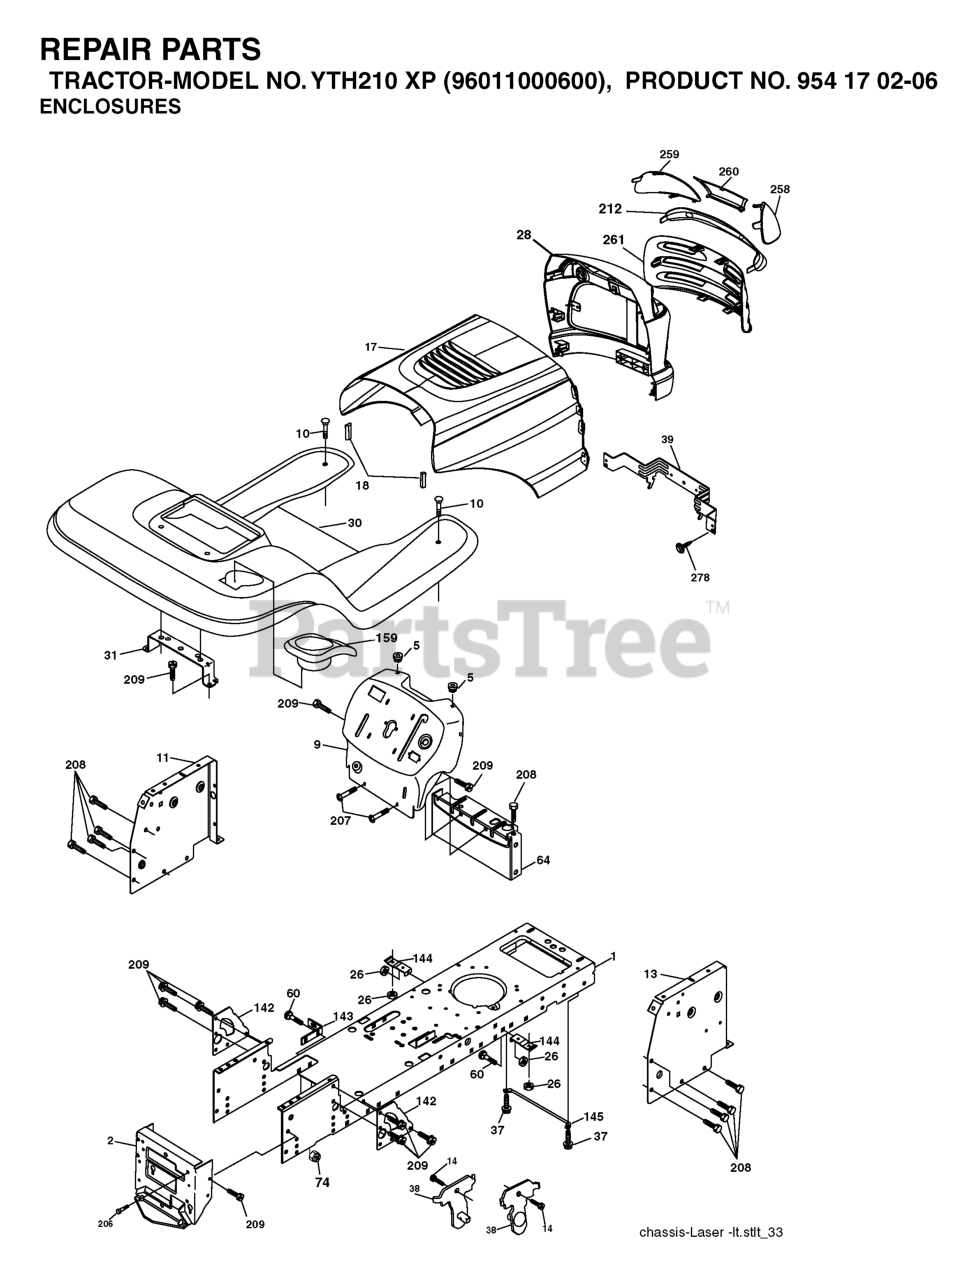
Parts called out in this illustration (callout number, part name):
1	CHASSIS STAMPING
2	DRAWBAR, 12GA
5	BUMPER.RUBBER.HOOD
10	BOLT D
11	PANEL.DASH.LH.LTX
13	PANEL ASM, DASH RH
17	VENT.HOOD.LASER.III
18	BUMPER.HOOD.LARGE.1.75"
20	PLATE MTG.BATTERY/FUEL TANK
23	BUSHING.SNAP.NYL.BLK.
26	NUT
30	FENDER STL W/CUPHOLDER
31	BRACKET.SUPPORT.FENDER
37	Screw 5/16-18 x 1/2 Hex, Self Tapping 5/16-18 x 1/2
38	BRACKET.ASM.PIVOT.MOWER.REAR
39	BRACKET PIVOT LASER
60	Bolt - Rd. Hd. Sq. Neckiage 3/8 16 x 3/4
64	DASH LOWER
90	NUT.PUSH.3/16
142	PLATE REINFORCEMENT
143	BRACKET, SWAYBAR CHASSIS
144	BRKT, FOOT REST
145	ROD PIVOT CHASSIS/HOOD
159	GREY CUP HOLDER
206	SHOULDER BOLT 5/16-18TT
207	SCREW, 5/16-18 X 1/2
208	SCREW 3/8-16X1/2
209	SCREW, 3/8-16X3/4
212	INSERT.LENS.REFLECTIVE
217	CONSOLE FUEL WINDOW
219	SCREW
258	LENS LH
259	LENS LH
260	COVER.LENS.HUSQ.LASER
272	VENT.HOOD.LASER.
273	VENT.HOOD.LASER.
278	SCREW
